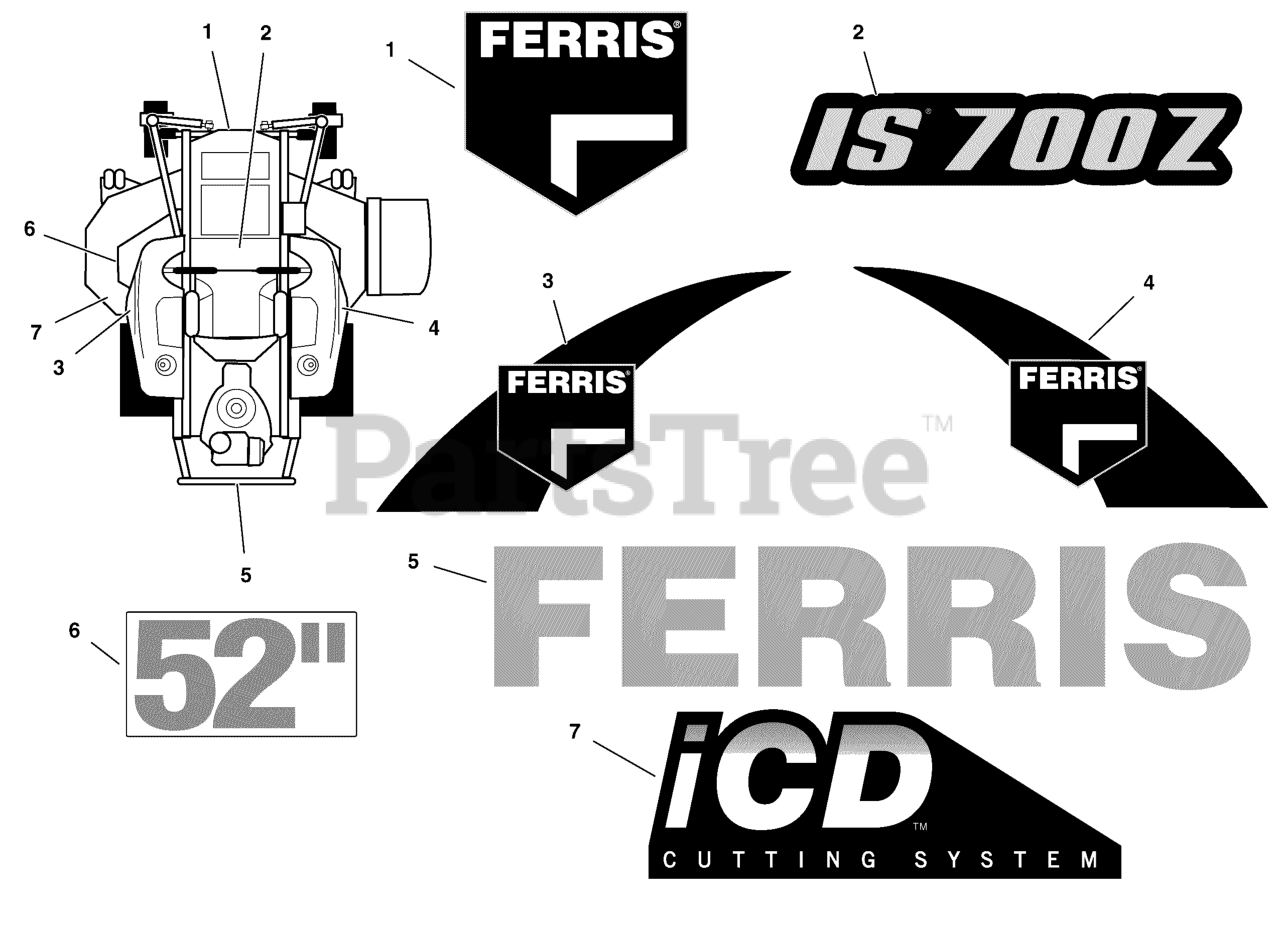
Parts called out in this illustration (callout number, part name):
1	DECAL, BRAND
2	DECAL, MODEL
3	DECAL, TANK, SML, LH, FERRIS
4	DECAL, TANK, SML, RH, FERRIS
5	DECAL, FERRIS, 2.23" X 11.39"
6	DECAL, 52
7	DECAL, iCD CUTTING SYSTEM
